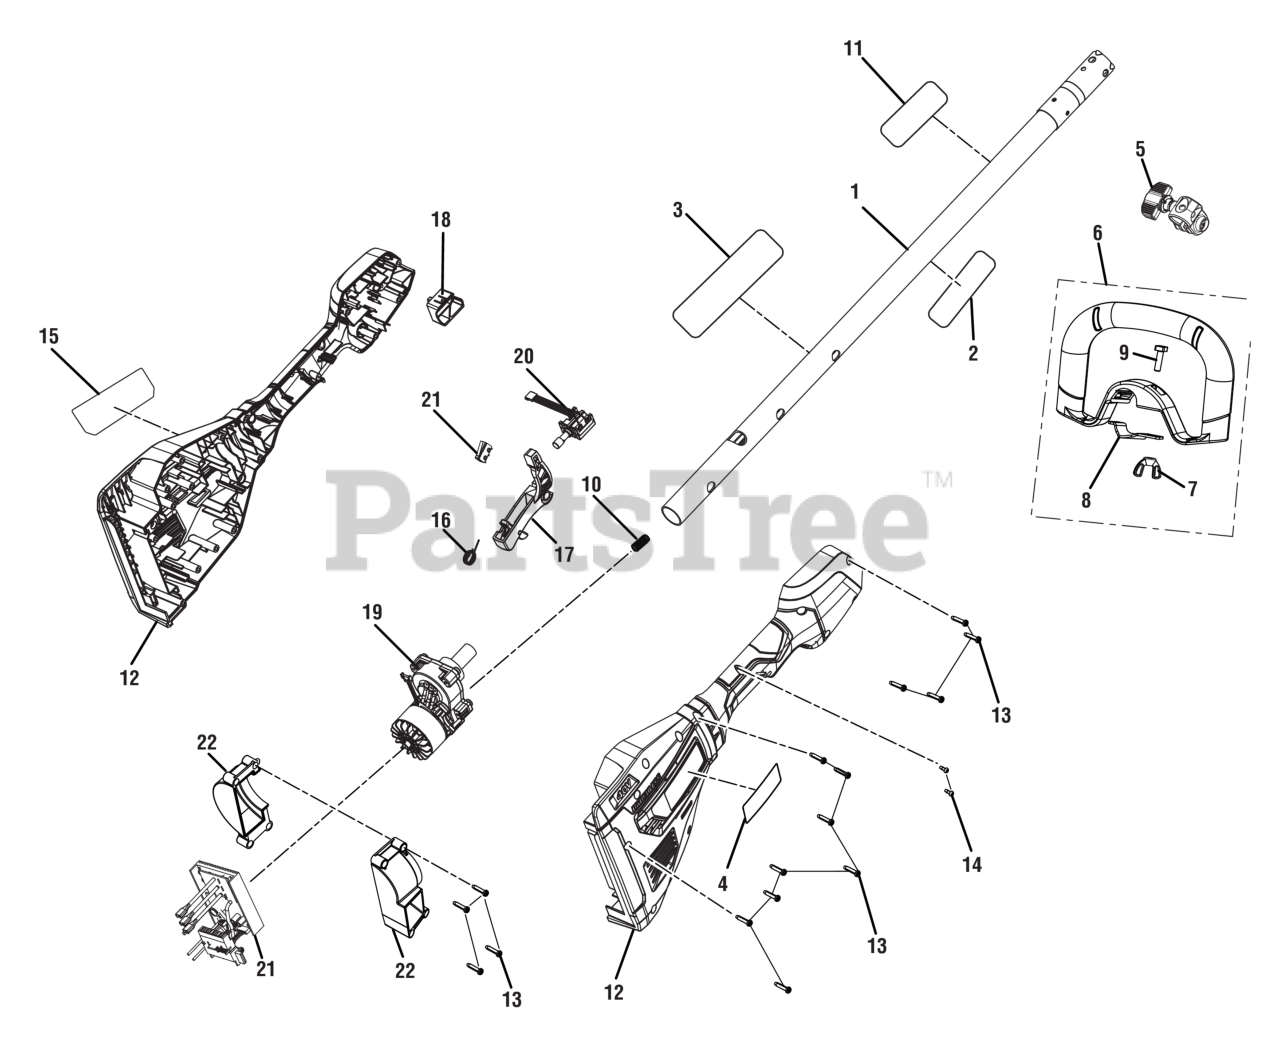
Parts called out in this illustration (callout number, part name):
1	Upper Boom Assembly (Inc. Key Nos. 2-3 & 11)
2	Warning Label (French/Spanish)
3	Icon Warning Label
4	Data Label
5	Boom Clamp Assembly
6	Front Handle Assembly
7	Wing Nut (1/4-20, Plastic)
8	Front Handle Clamp
9	Bolt (1/4-20 x 1 in., Square Hd.)
10	COMPRESSION SPRING
11	Attachment Label
12	Rear Handle Assembly (Inc. Key Nos. 4 & 15)
13	Screw (M4 x 18 mm, T15 Torx Pan Hd.)
14	Screw (M3 x 8 mm, Pan. Hd.)
15	Logo Label
16	Spring, Torsion, Dia 12.5mm, Music Wire
17	Trigger and Lock Out Button Assembly
18	High-Low Speed Switch Trigger
19	Motor and Gear Box Assembly
20	Variable Speed Switch
21	Electric Controller and Switch Assembly
22	Motor Volute Assembly
